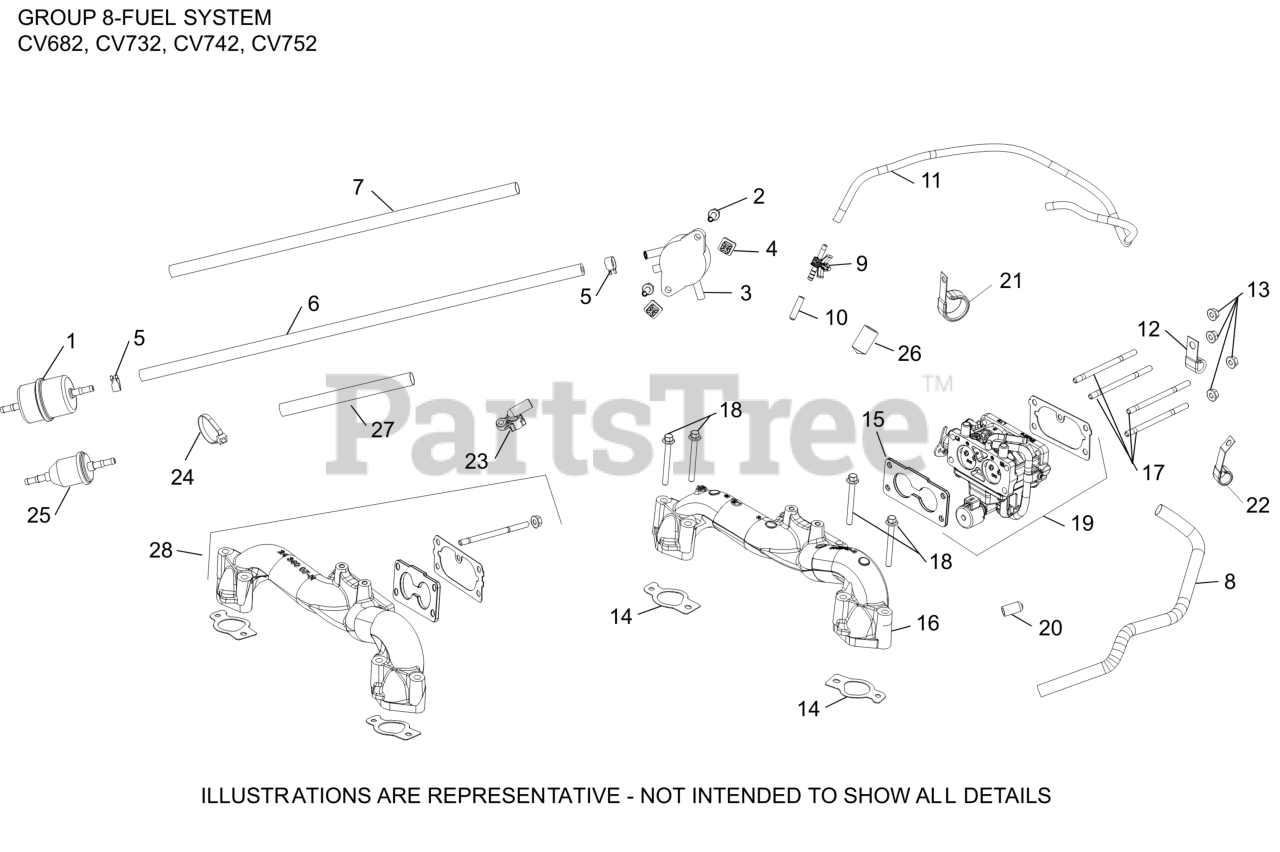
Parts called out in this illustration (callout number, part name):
1	FILTER, FUEL
2	SCREW, HEX HEAD
3	PUMP, FUEL
4	NUT, PLASTIC - BLACK
5	SPRING CLAMP, HOSE
6	HOSE,LW PERM.FUEL 24.00"-USE 25 111 81-S
8	SLEEVE, INSULATING 14"
8	SLEEVE, ANTI-ABRASION
9	CONNECTOR, EVAPORATIVE
10	CAP, MASKING
11	HOSE, EVAPORATIVE
13	NUT, FLG M6X1.0
14	KIT, INTAKE MANIFOLD GASKET
15	GASKET, CARBURETOR
16	KIT, MANIFOLD INTAKE (VERT 2BBL)-DISC.
17	STUD,M6X1.0X96
18	SCREW, HEX FLANGE
19	KIT, CARBURETOR
27	SLEEVE, ANTI ABRASION-USE 25 431 12-S
NI	KIT, HIGH ALT(4000 TO 8000 FT)
NI	KIT, ACCEL PUMP REPAIR
NI	KIT, CARBURETOR REPAIR
NI	KIT, FLOAT BOWL REPLACEMENT
NI	KIT, FUEL SHUTDOWN SOLENOID
NI	KIT, SOLENOID
NI	KIT, CHOKE REPAIR
